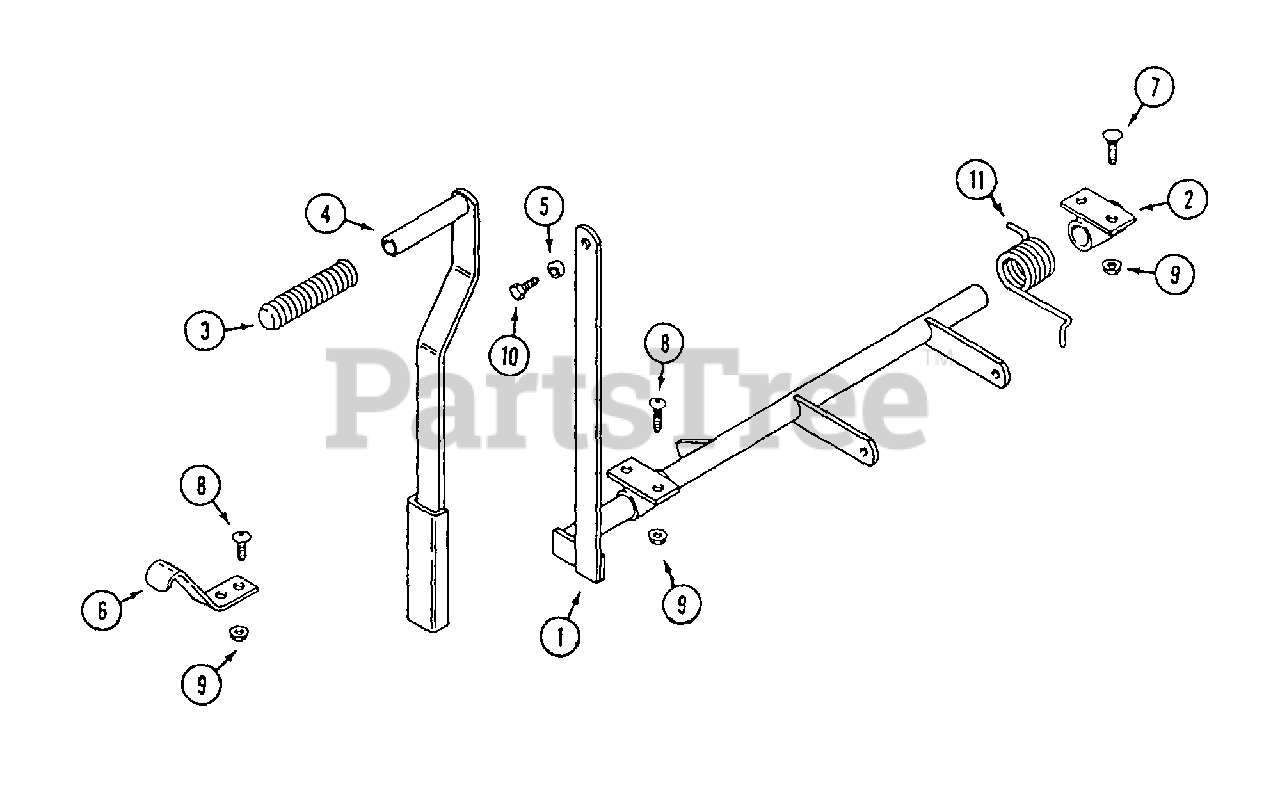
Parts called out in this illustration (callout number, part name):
3	GRIP - handle
4	EXTENSION - lift lever, upper
6	BRACKET - lever lock down
7	BOLT - carriage 5/16" - 18 x 3/4"
8	SCREW - 5/16" - 18 x 5/8" allen head
9	NUT - 5/16" - 18 flange lock
10	BOLT - 1/4" - 20 x 1/2"
11	SPRING - torsion
